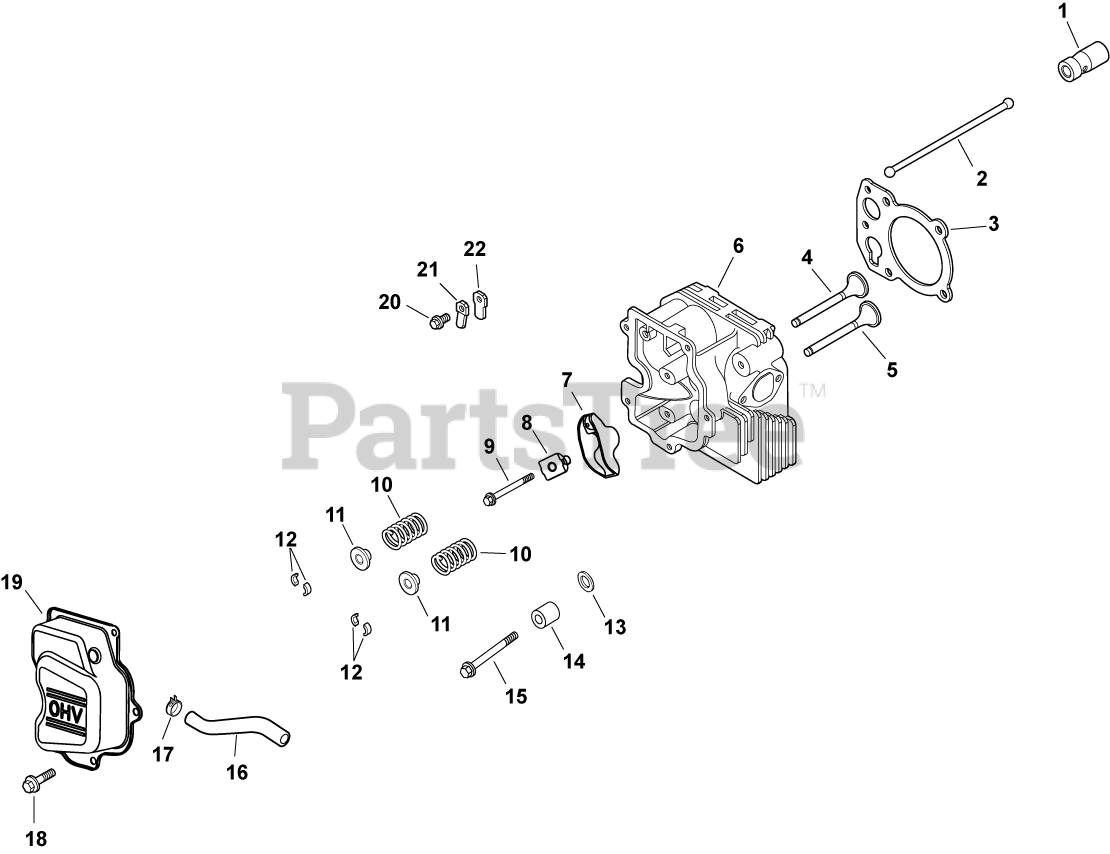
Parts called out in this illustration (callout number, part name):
1	LIFTER, HYDRAULIC VALVE-USE 25 351 10-S
2	ROD, PUSH - DISCONTINUED
3	GASKET, CYLINDER HEAD
4	VALVE, INTAKE
5	VALVE, EXHAUST
6	HEAD ASSEMBLY, CYLINDER
7	ARM, ROCKER
8	PIVOT, ROCKER ARM
9	SCREW, FLG M6X1.0X34
10	SPRING, VALVE
11	RETAINER, VALVE SPRING - USE 25 173 28-S
12	KIT, RETAINER
13	WASHER, FLAT 13/32"
14	SPACER, HEAD BOLT EXHAUST PORT
15	SCREW, CYLINDER HEAD (M10 X 80)
16	HOSE
17	CLAMP, HOSE (KM)-USE 25 237 31-S
18	SCREW,FLG THD FRM M6X1.0X16-(#25086397S)
19	COVER, ROCKER
20	SCREW, FLG THD FRM M5X.8X10
21	RETAINER, REED
22	REED, BREATHER
1201602-S	VALVE, EXHAUST (.25 MM)
1201702-S	VALVE, INTAKE (.25 MM)
1232630-S	HOSE, BREATHER
